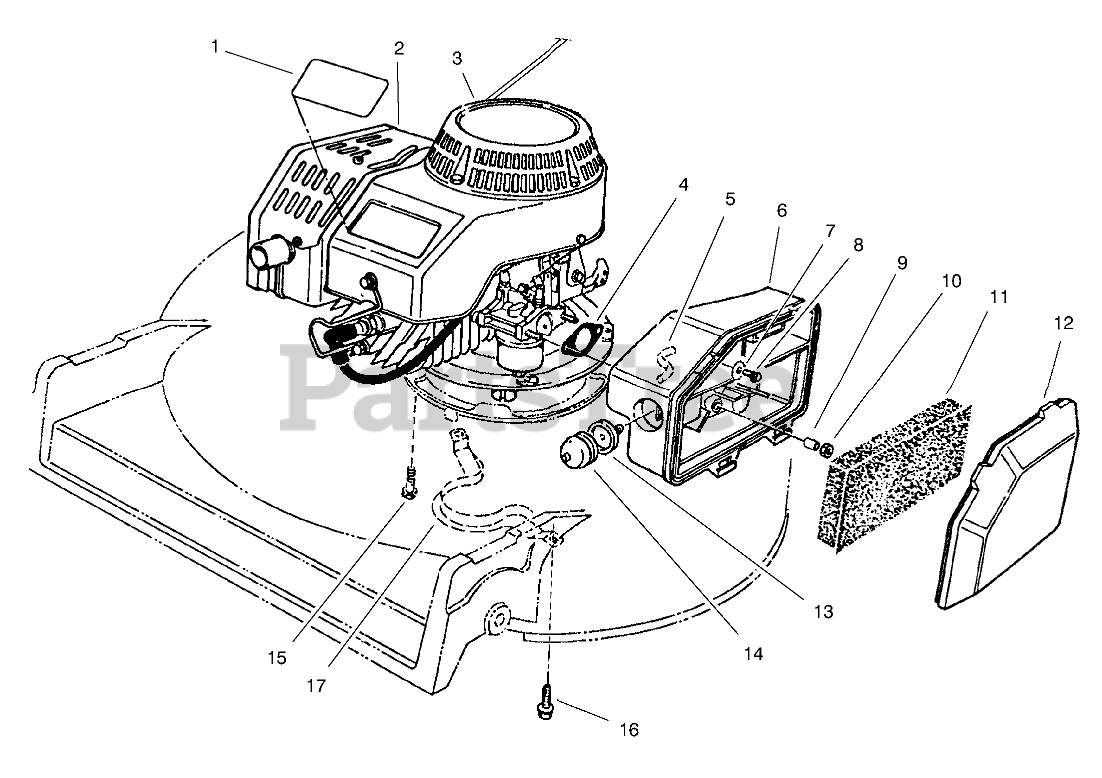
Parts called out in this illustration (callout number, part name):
1	DECAL - PROLINE
2	ENGINE ASM - BBC 2 CYCLE
3	DECAL-2 CYC RECOIL COMM
4	GASKET-AIR CLEANER
5	HOSE-PRIMER
6	BODY-AIR CLEANER
7	WASHER-FLAT
8	SCREW-HH
9	SPACER
11	ELEMENT-AIR CLEANER
12	COVER-AIR CLEANER
13	BODY-PRIMER
14	BULB-PRIMER
15	SCREW-HHF
16	SCREW-HWHTF
17	Guide-Belt
